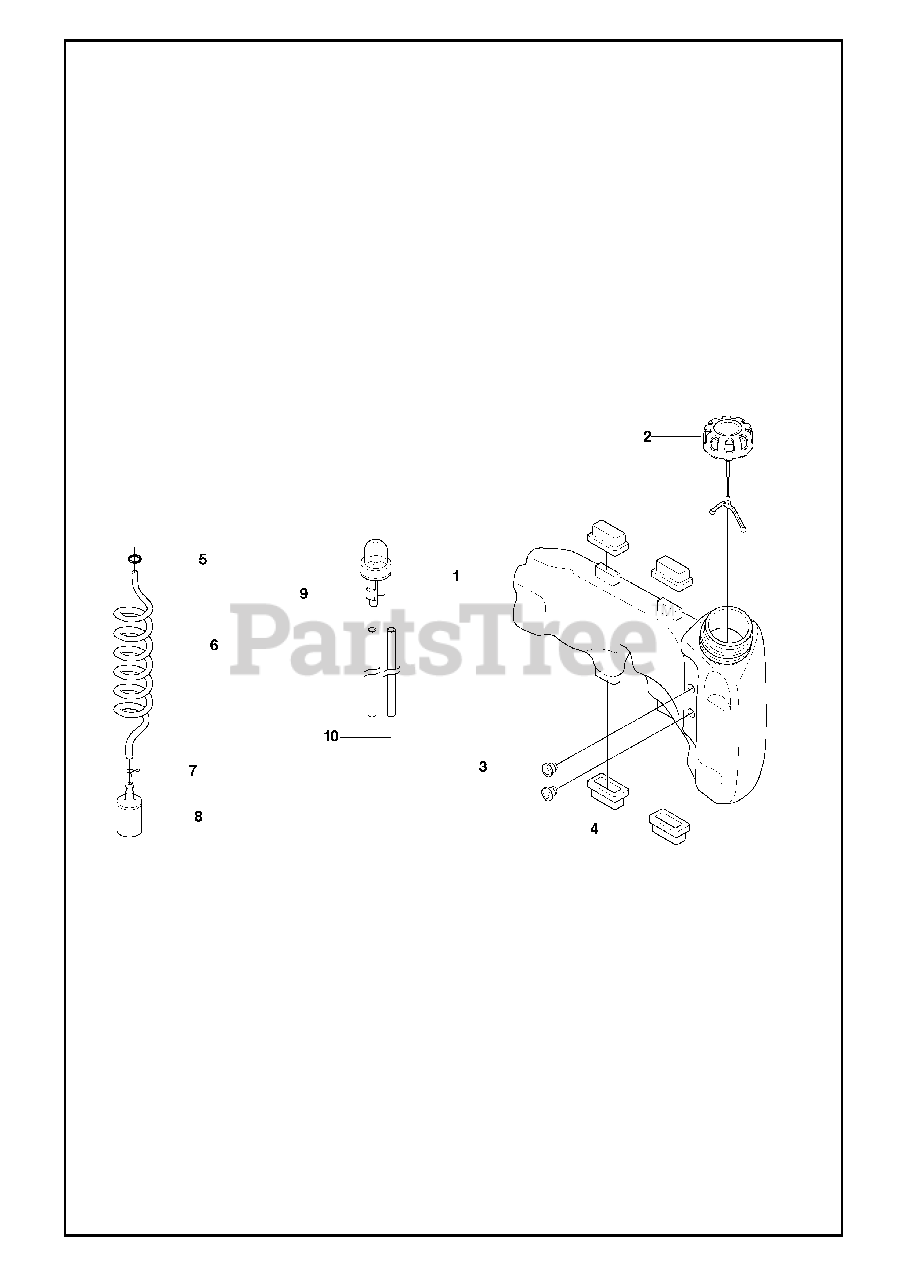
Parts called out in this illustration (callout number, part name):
3	FUEL TANK BUSHING
6	FUEL HOSE
7	HOSE CLAMP
8	FUEL FILTER
9	AIR PURGE BUBBLE
10	HOSE
